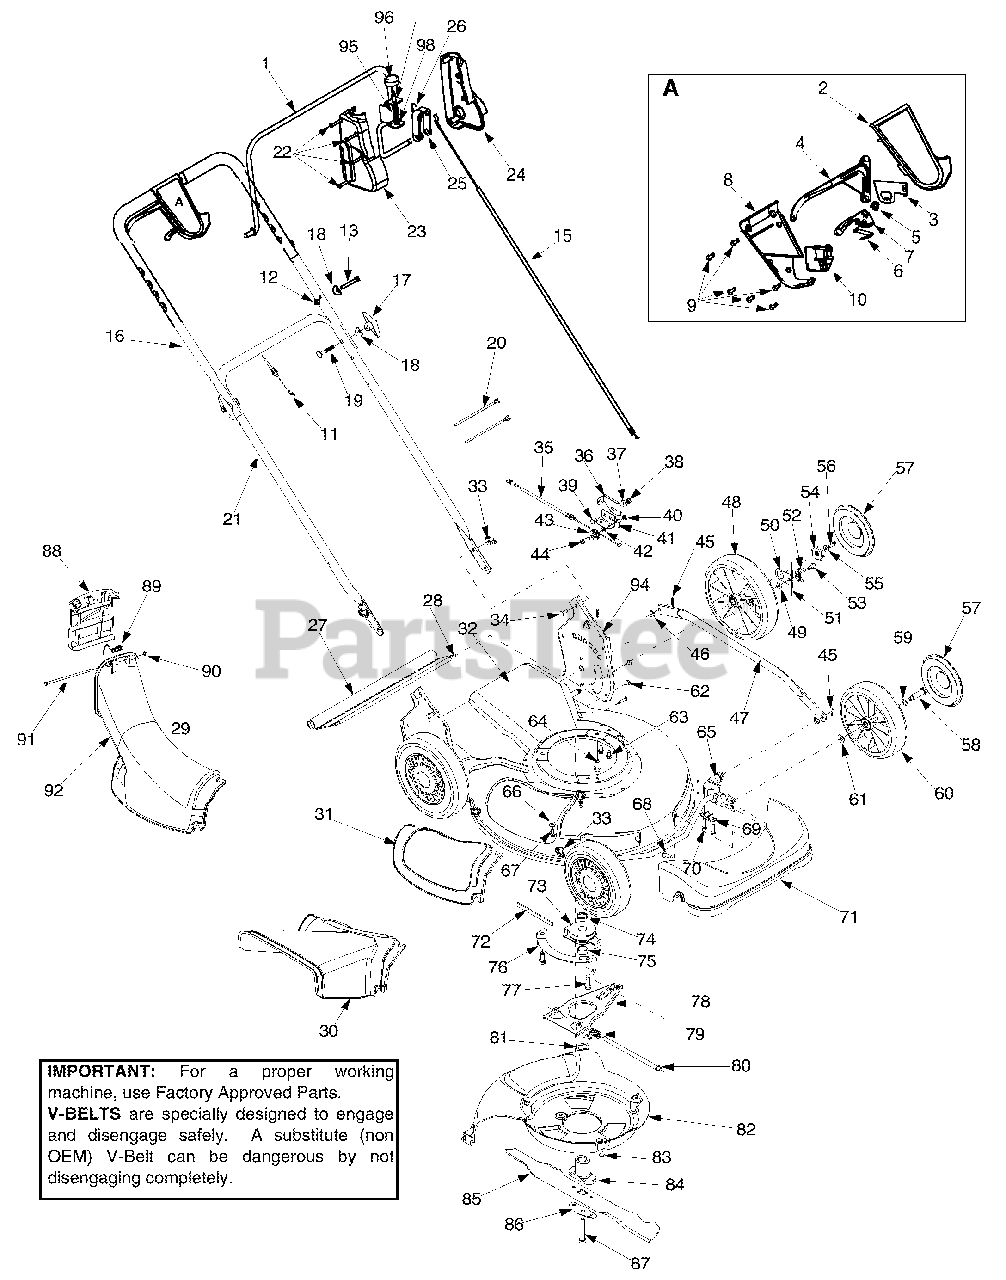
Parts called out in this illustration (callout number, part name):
2	Upper Control Handle
3	6 Spd. Rack Cable Bracket
4	Control Lever
5	Gear Insert
6	Shift Lever Spring
7	6 Speed Shift Lever
8	Lower Control Housing
9	C Sunk Tap Screw #10 x .75 Lg
10	Cable Mounting Cap
11	Drive Cable 51.0
12	Hex Lock Nut 1/4-20 Gr. 8
13	Hex Hd. Cap Screw 1/4-20 Gr. 5
15	Control Cable 58.25"
18	Saddle Washer .320 ID x .830 OD
19	Carriage Bolt 5/16-18 x 2.0
20	Cable Tie
22	Hi-Low Screw
23	Control Cover RH
24	Control Cover LH
26	Torsion Spring
27	Trail Shield
28	Trail Shield Wire
29	Chute Assembly
30	Side Discharge Chute
31	Mulch Cover
34	Carriage Bolt 1/4-20 x .75
35	6 Speed Cable
38	Hex Nut 1/4-20
39	Carriage Screw 1/4-20 x .50
40	Hex Nut 1/4-28
43	Roller Cable
44	Shoulder Screw .375 ID x 1/4-14
45	Cotter Pin
46	Bowed Washer
48	Wheel 9 x 2
49	Top Lock Tab Weld Nut 1/4-20
50	Ratchet Pawl Plate
51	Plastic Spring Ratchet
53	Shld Screw .340 ID x .285 OD
54	Wheel Rachet
55	Bell Washer .265 ID x .75 OD
56	Hex Cap Screw 1/4-20 x .620
57	Hubcap
58	Shoulder Screw .498 x 1.445
59	Wave Washer .510 ID x .750 OD
60	Wheel 8 x 2
61	Spring Washer .401 ID x .870 OD
62	Screw 1/4-14 x .500
63	Screw 1/4-14 x .625
64	Hex Washer Screw 3/8-16 x 1.0
66	Flat Washer .344 ID x .62 OD
67	Carriage Screw 1/4-20 x .75
68	Torx Screw
69	Block Bushing
70	Hex Washer Screw
71	Front Axle Cover
72	Belt 3/8 x 39.24
73	Pulley Assembly
74	Sleeve Spacer .88 ID x 1.13 OD
75	Sleeve Spacer .88 ID x 1.00 OD
77	Screw 3/8-18 x 1.0
80	Pivot Shaft
81	Wave Washer 1.38 ID x .88 OD
82	Baffle
83	Screw 1/4-20 x 3.75
84	Blade Adapter Kit
85	21" Mulching Blade
86	Blade Bell Support
87	Hex Bolt 3/8-24 x 2.5
88	Chute Door
89	Torsion Spring
91	Pivot Rod
92	Discharge Chute
